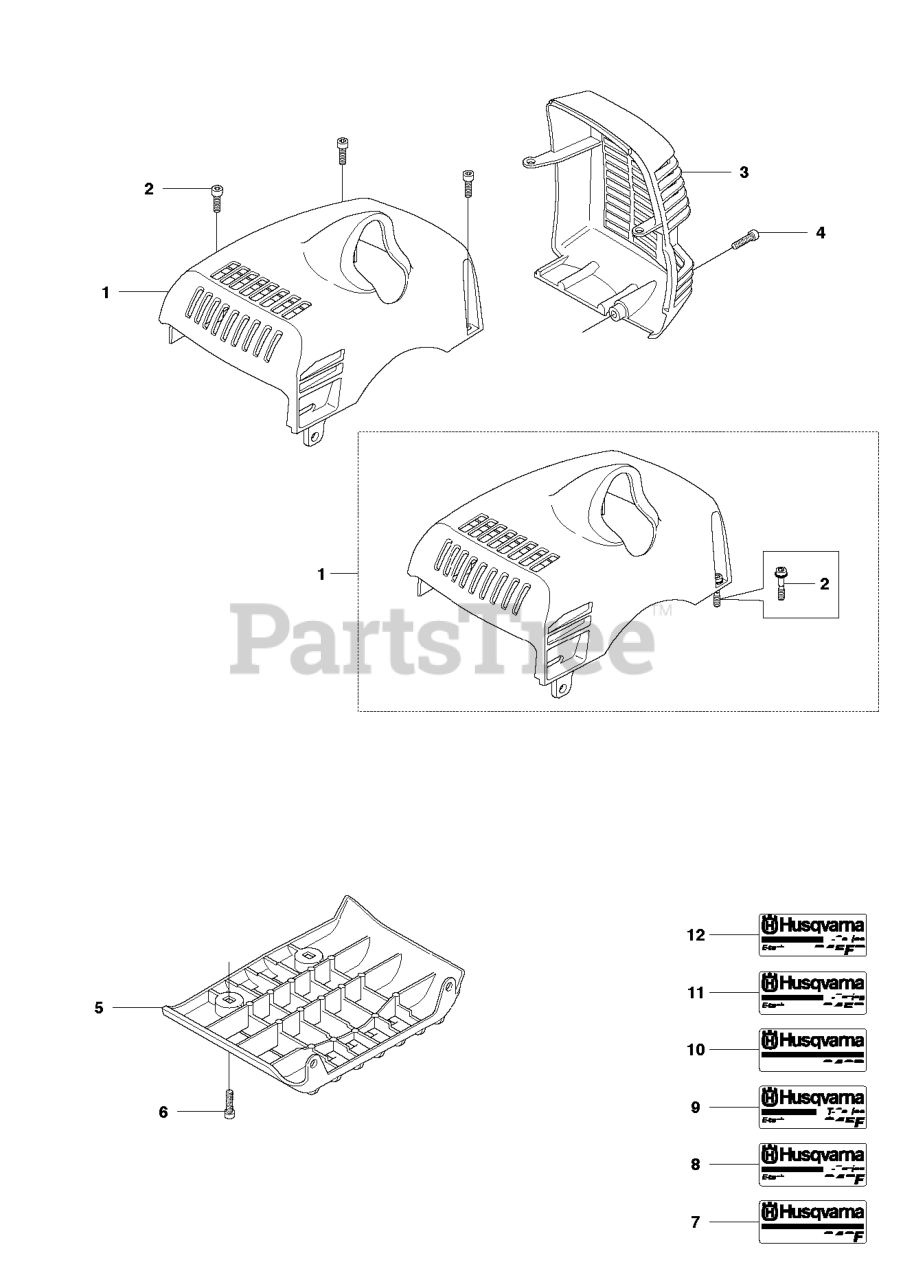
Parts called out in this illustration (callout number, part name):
1	CYLINDER COVER
1	CYLINDER COVER ASSY
2	SCREW IHSCFMO
2	SCREW IHSCFM
3	MUFFLER COVER
4	SCREW IHSCFM
6	SCREW IHSCFM
7	LABEL
8	DECAL
9	DECAL
10	DECAL
11	DECAL
12	LABEL
